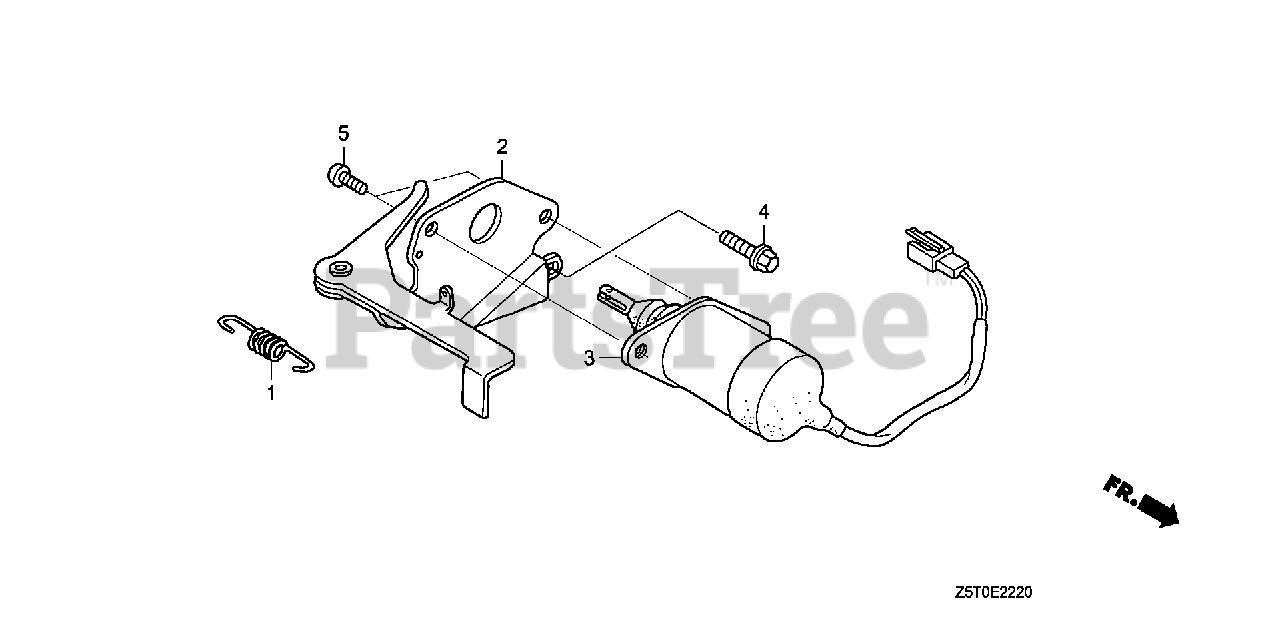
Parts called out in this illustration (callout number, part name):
1	SPRING, CHOKE RETURN
2	LEVER, THROTTLE
3	SOLENOID ASSY.
4	BOLT, FLANGE (6X12) (CT200)
5	SCREW, PAN (5X8)
